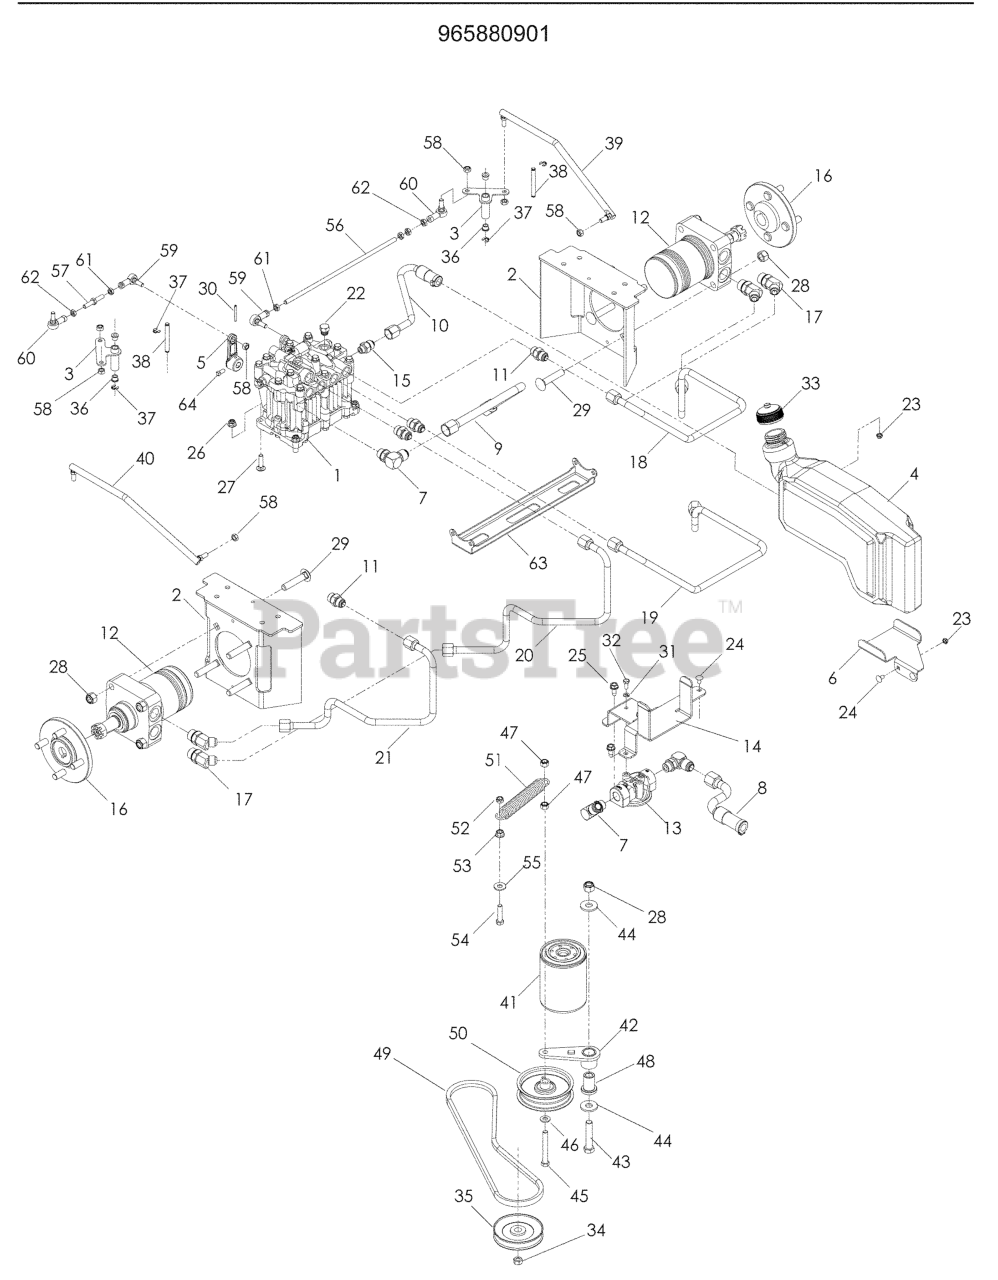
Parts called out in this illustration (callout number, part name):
1	PUMP, DUP10S (77808041201)
2	MOUNT WHEEL MTR BLK
3	ASM MOTN BELLCRK
4	RESERVOIR, HYDRAULIC
6	HOLD LIST SUP RESERVIOR FT-BLK
8	LINE, HYD, SUCTION
9	LINE, HYD, CHARGE
10	LINE, HYD, CASE
11	FITTING, STRAIGHT F6400-8-8-0
12	WHEEL MOTOR
13	FILTER HEAD
14	HOLD LIST SUP RESERVOIR RR-BLK
15	FITTING, HYDRO
16	HUB.WHEEL.ZTR
17	ELBOW-ADJ 45 DEG F6802-8-10
18	LINE, HYD, D
19	LINE, HYD, C
20	LINE, HYD, B
21	LINE, HYD, A
22	PLUG, 6408-6
23	JAM NUT 1/4C (2 2 PW01)
24	RHSSNB 1/4-20 X 1/2
25	BOLT 5/16-18 X 3/4
26	5/16-18 NYLOC FLANGE NUT
27	BOLT, CARRIAGE 5/16X1-1/4
28	NUT 1/2-13 HEX NYLOC ZD
29	RHSNB 1/2 - 13 X 2 - 1/2 GR5
30	PIN, SPIRAL, 5/32 X 1 1/2
31	LOCKWASHER 1/4"
32	HCS 1/4C X 5/8
33	HYDRAULIC CAP
34	NUT M10-1.5 L/H HEX
35	PULLEY, PUMP
36	BUSHING, BAIL 5/16
37	RING RETAINING EXT 5/16
38	PIN, MOTION
39	LINK MTN CTL, FT-LT
40	LINK MTN CTL FT-RT
41	HYDRAULIC OIL FILTER
42	RP.IDLER ARM WELDMENT
43	HEX SCREW 1/2-13 X 2.5" GR 5
44	WASH USS FLAT 1/2
45	TAPBOLT, 3/8C X 3
46	WASHER 3/8 SAE FLAT
47	NUT 3/8-16 NYLOC
48	PIVOT, IDLER
49	V-BELT 61" SPINDLE DRIVE
50	PULLEY IDLER
52	NUT HEX 3/8-16 NYLON, THIN
53	NUT 3/8C WHIZ
54	TAP BOLT 3/8C X 1.5
55	WASHER 3/8 FLAT
56	ASM MTN LINK RR-LT
57	ASM MTN LINK RR-RT
58	NUT 5/16-24 TOP LK GRC ZD
59	SPHERICAL ROD END, RH
60	SPHERICAL ROD END, LH
61	NUT 5/16F LEFTHAND
62	NUT 5/16-24 UNF HEX JAM
63	SUPPORT WHEEL MOTOR BLACK
64	SCREW 5/16C X 5/8 SQ HEAD
